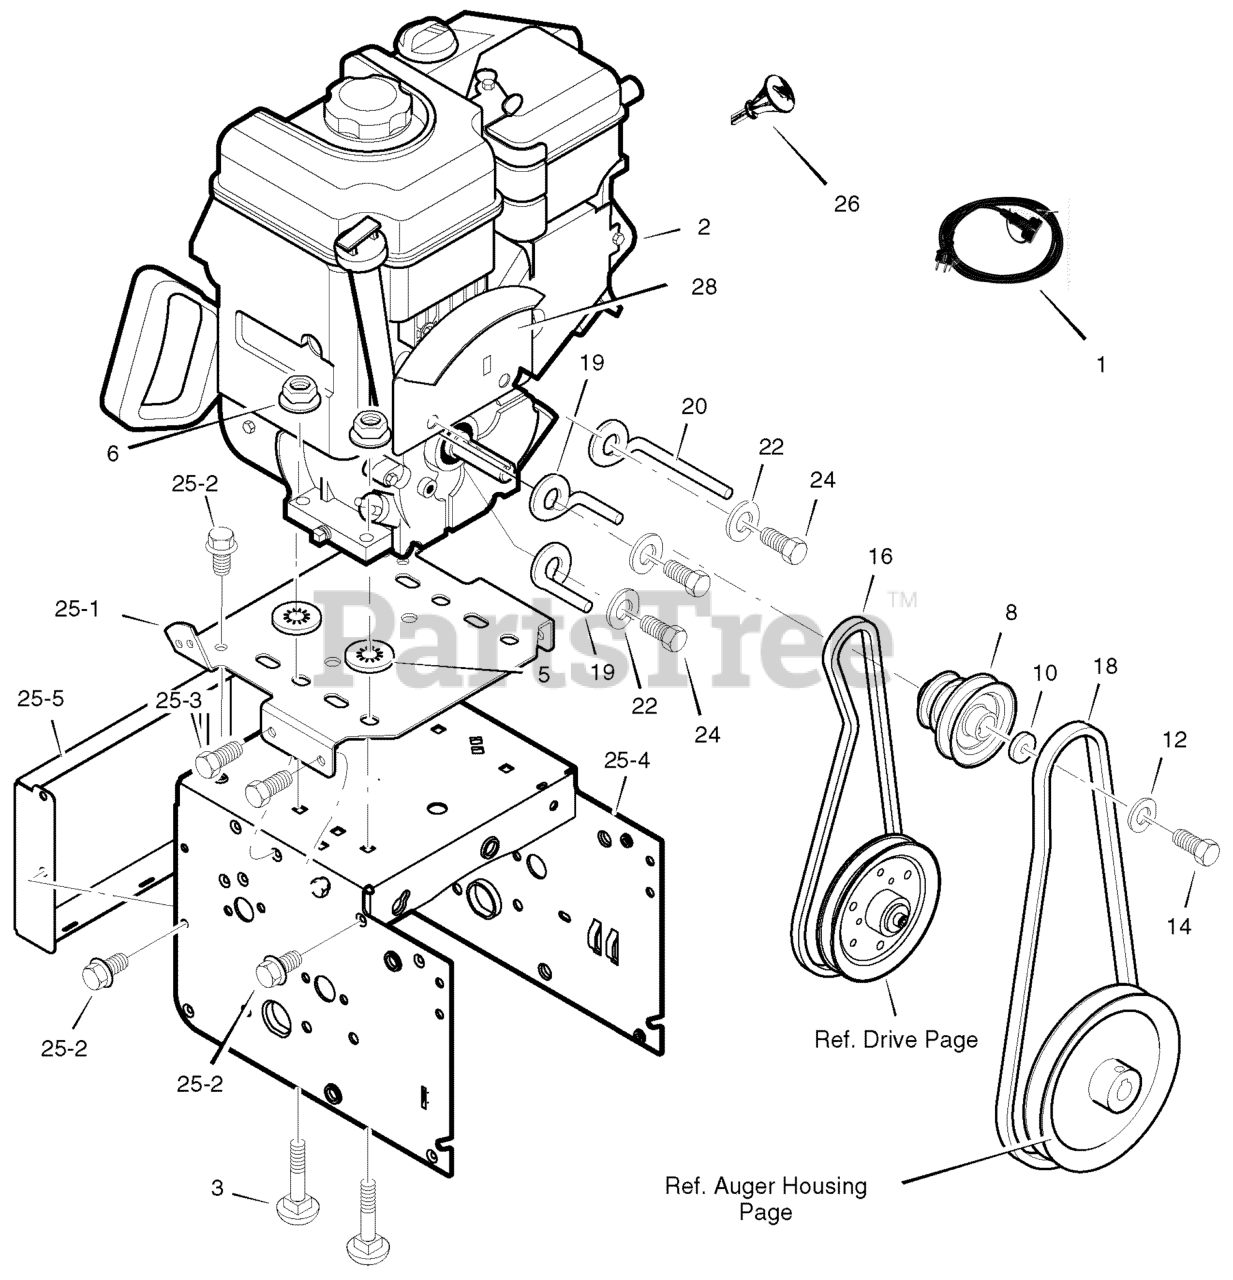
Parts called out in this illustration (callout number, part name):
1	CORD, STARTER
2	ENGINE
3	BOLT, CARRIAGE 5/16-18
5	RETAINER, PUSH
6	NUT, HEX 5/16-18
8	PULLEY, ENGINE
12	WASHER .38ID
14	SCREW, 3/8-24 x 1.00
16	BELT, HYDRO DRIVE
18	BELT, AUGER V 4L
19	GUIDE, BELT
20	GUIDE, BELT
22	WASHER, SPTLK .31X.58X.08
24	SCREW, 5/16-24 x 0.75
25	FRAME ASSEMBLY
25-1	PLATE, ENGINE MOUNT
25-2	SCREW, TAP 1/4-20 X .63
25-3	SCREW, TAP 5/16-18 X .50
25-4	FRAME, MOTOR BOX
25-5	PANEL, BACK - HYDRO
26	KEY, ENGINE
28	PLATE, BELT GUARD
